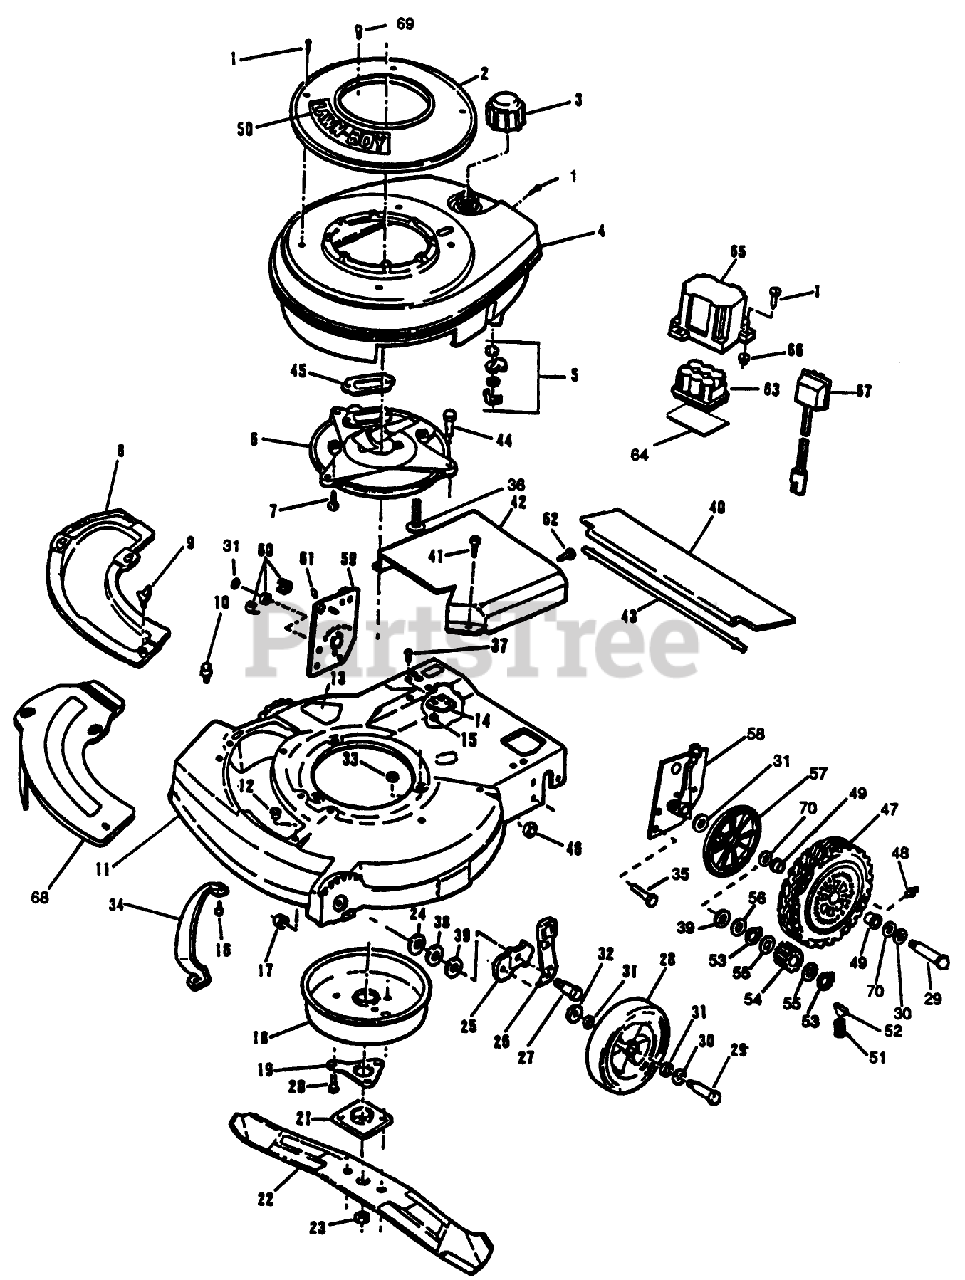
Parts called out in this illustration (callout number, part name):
1	SCREW - SELF TAPPING
2	STARTER BASE&NUT*B
3	FUEL CAP & INSERT
5	SHUT OFF VALVE KIT
7	SCREW V
9	WING SCREW LAWRE
11	HOUSING ASM
14	BOLSTER
15	LOCKNUT E
18	MUFFLER COVER F
19	SUPPORT F
20	SCREW
21	PLATE AND COLLAR ASM
23	NUT-BLADE
24	WASHER
26	SPRING ARM ASM
27	BOLT
29	BOLT WHEEL
30	SPACER
31	WASHER
32	WASHER WROUGHT
33	NUT-LOCK F
34	BAR-TOE
36	SCREW-SEMS F
38	WASHER
39	WASHER
40	SHIELD-TRAILING
41	SCREW SEMS TRM HEX HD
44	SCREW-HH
46	NUT-LOCK F
48	FITTING LINCOLN
51	SPRING
52	KEY
53	RET RING
54	PINION BROCKWAY
55	SPACER/GR ALGHNY
56	THRUST WASHER
59	HEIGHT ADJ AY-RH
60	REAR AXLE BEARING
61	**FITTING LINCOLN
64	PAD-BATTERY
66	NUT-CLIP
69	SCREW SEMS SM
70	WASHER-FELT
